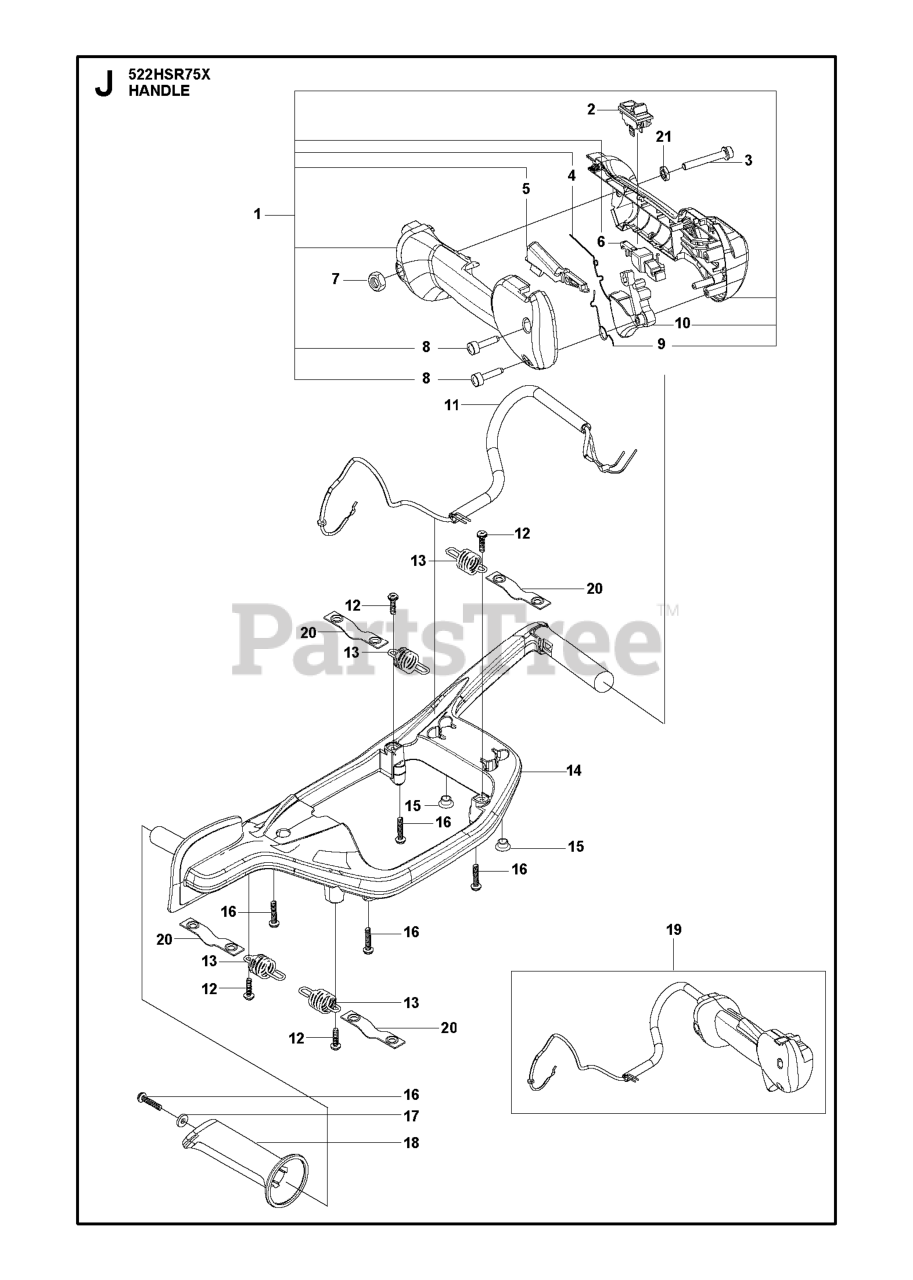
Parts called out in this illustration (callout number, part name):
1	THROTTLE HANDLE ASSY HVA, SPA
2	STOP BUTTON
3	SCREW IHSCFM
5	THROTTLE LOCKOUT
6	BUTTON BLIND BUTTON
8	SCREW IHSCT MT4X18 10.9 ZN/FE
10	THROTTLE CONTROL
15	RIVET TUBULAR
17	WASHER 5.3X15
18	HANDLE GRIP FRONT BLACK
